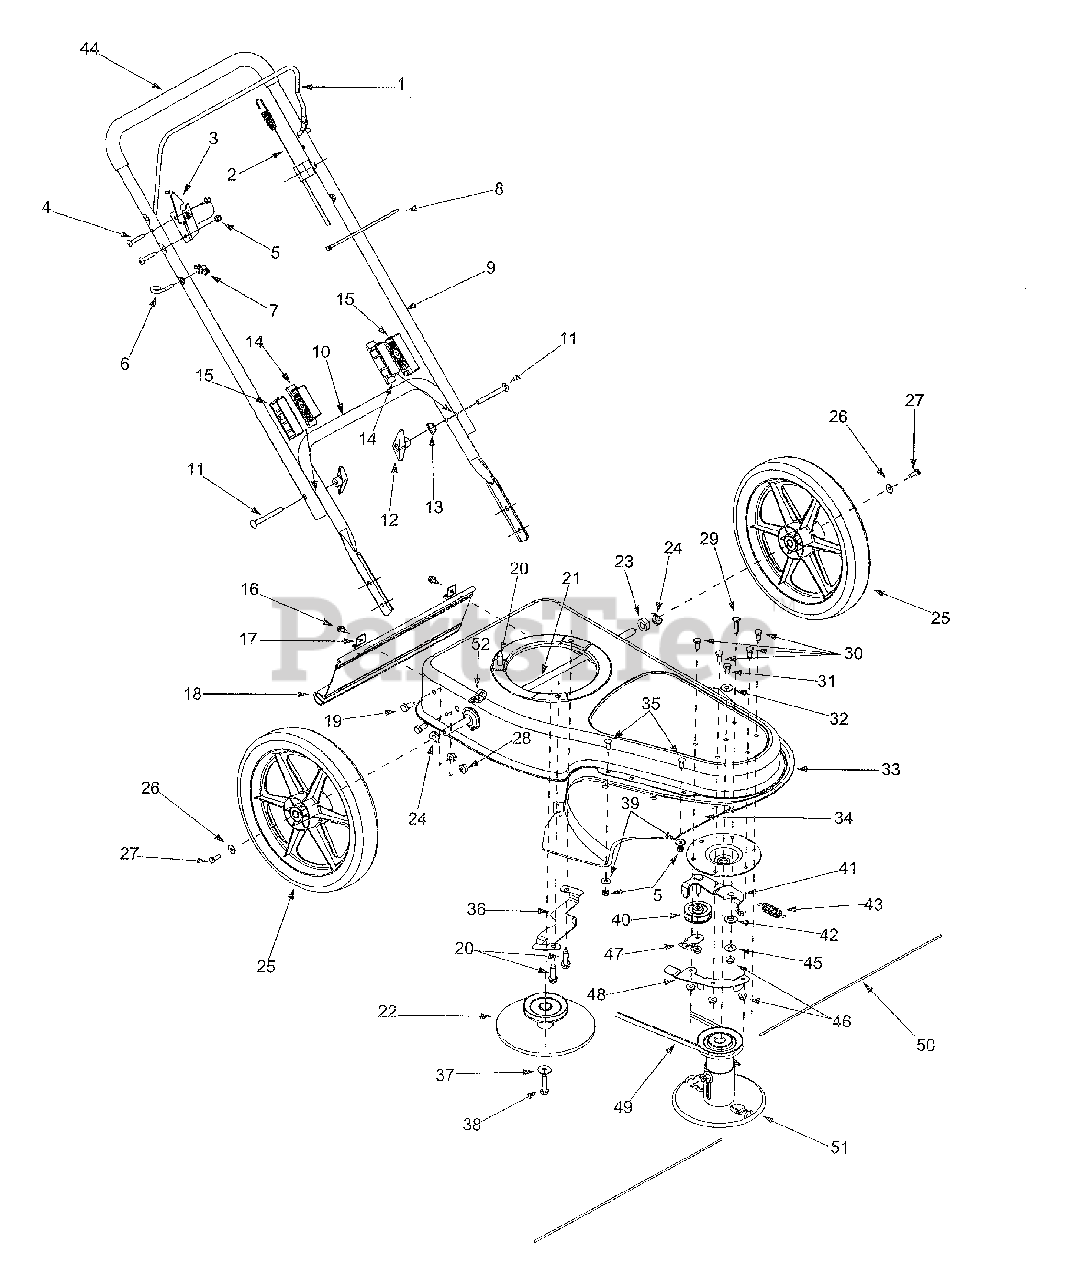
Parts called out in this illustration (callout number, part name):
2	Engagement Cable
3	Control Lock Bracket
4	Machine Screw 1/4-20 x 1.50
5	Hex Lock Nut 1/4-20
6	Eye Bolt 1/4-20
8	Cable Tie
13	Shoulder Washer .320 ID x .93 OD
14	Lower Handle Connector
15	Upper Handle Connector
16	Hex Washer Screw 1/4-14 x .625
17	Trail Shield Clip
18	Trail Shield
19	Hex Cap Screw 3/8-16 x .750
20	Hex Washer Screw 3/8-16 x 1.25
21	Trimmer Axle
22	Flywheel Pulley
23	Spacer .51 ID x 1.0 OD
24	Spacer Washer .501 ID x 1.0 OD
25	Wheel Assembly
26	Bell Washer .265 ID x .75 OD
27	Hex Cap Screw 1/4-20 x .75
28	Flange Lock Nut 3/8-16
29	Screw 5/16-18 x 1.25
30	Screw 5/16-18 x .75
31	Hex Cap Screw 5/16-24 x .625
32	Bell Washer .325 ID x .930 OD
35	Hex Carriage Screw 1/4-20 x .75
38	Hex Cap Screw 3/8-24 x 1.50
39	Flat Washer .28 ID x .74 OD
40	Idler Pulley
41	Idler Bracket Assembly
42	Idler Spacer
43	Extension Spring .50 Dia x 1.88 Lg
44	Handle Grip
45	Flat Washer
46	Flange Lock Nut 5/16-18
49	V-Belt
50	.155 Dia. x 22'' Trimmer Line 24-Pack
51	Spindle Assembly
52	Cable Retainer Clip
